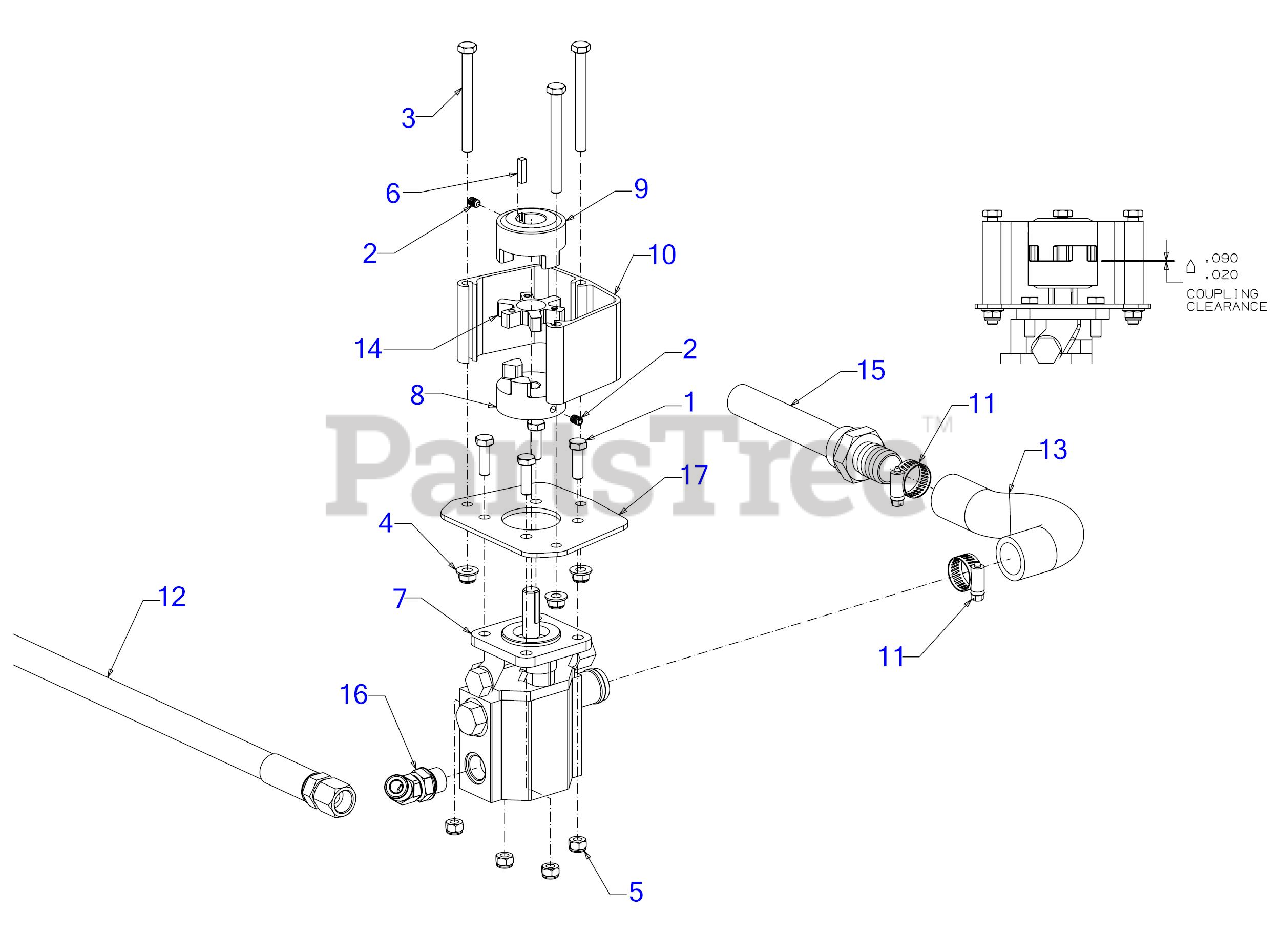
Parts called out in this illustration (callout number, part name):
1	SCREW 5/16-18 x 1.0 GR5
2	SCREW 1/4-20 x .38
3	SCREW 5/16-18 x 3.25 GR5
4	FLANGE LOCK NUT 5/16-18
5	HEX NUT
6	SQUARE KEY 3/16 x .7
7	LOGSPLITTER GEAR PUMP 11GPM
8	LOGSPLITTER COUPLING .500
9	LOGSPLITTER COUPLING .875
10	COUPLING SHIELD
11	HOSE CLAMP-5/8
12	48" HYDRAULIC HOSE
13	INLET HOSE
14	SPIDER COUPLING BUSHING
15	INLET FILTER
16	HYDRAULIC FITTING
17	SUPPORT BRACKET
